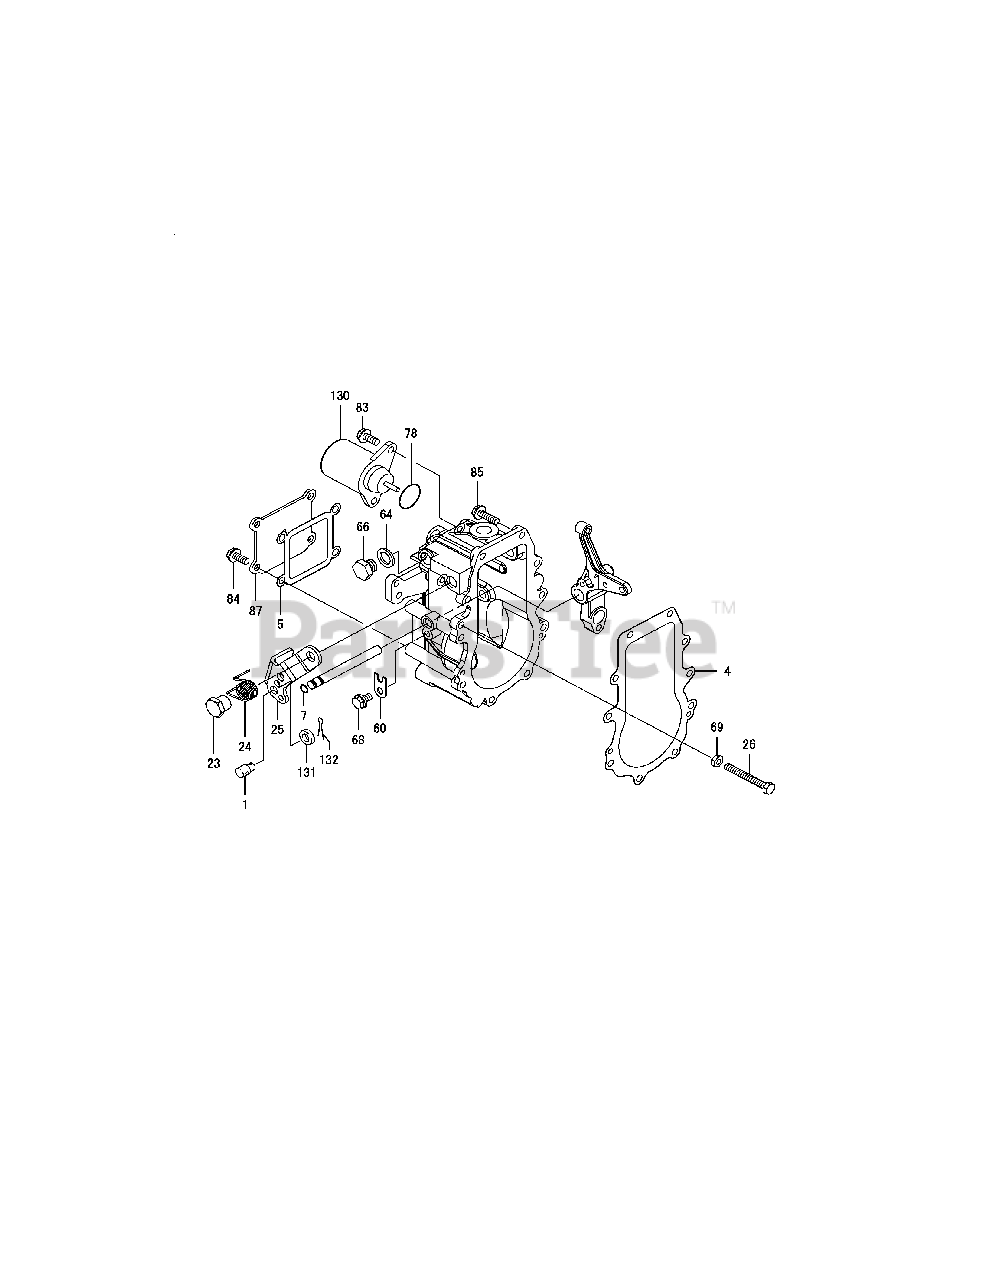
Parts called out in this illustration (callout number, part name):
25	LEVER, REGULATOR
26	BOLT, IDLE LIMIT
60	RETAINER, SHAFT
64	SEAL WASHER 12(BOLT)
68	BOLT 6X 10 PLATED
83	BOLT M 6X 14 PLATED
84	BOLT M 6X 14 PLATED
85	BOLT M 6X 20 PLATED
130	SOLENOID, STOP
131	WASHER 8, POLISHED
132	COTTER PIN 1.6X18
